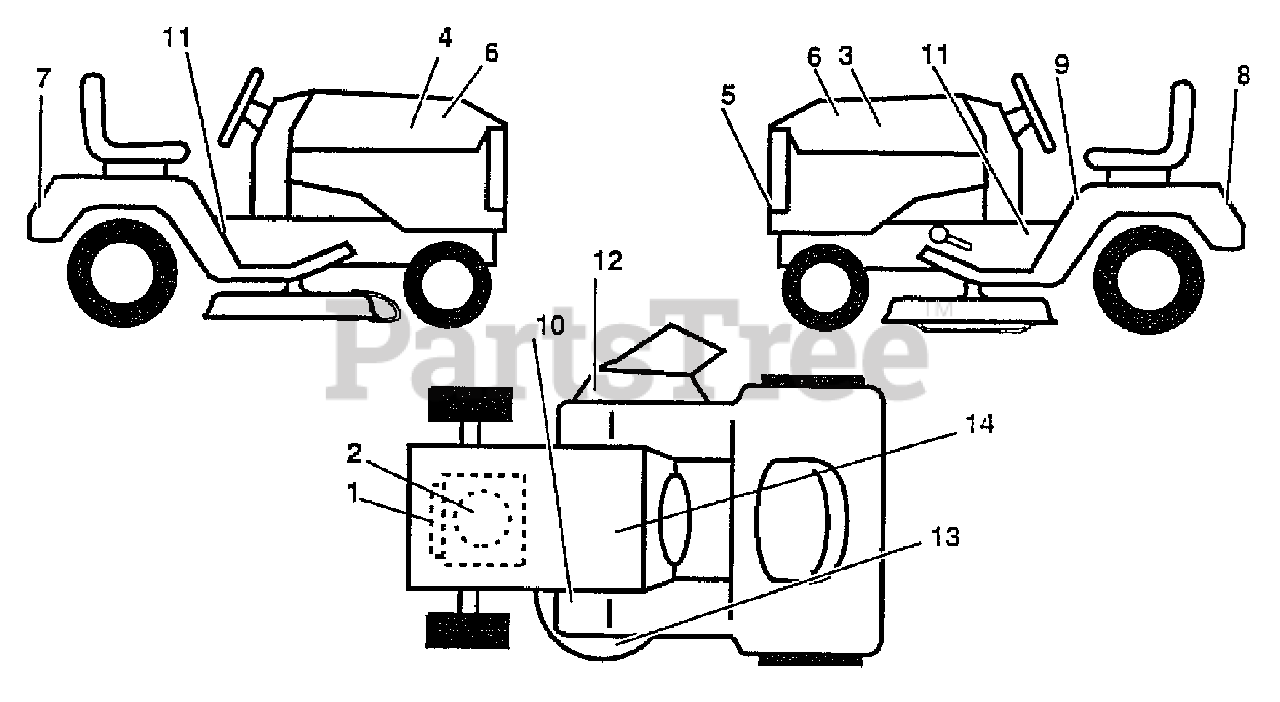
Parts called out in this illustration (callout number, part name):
1	Decal, Engine Instruction
2	Decal, Air Cleaner, HP
3	Decal, Hood Stripe, L.H.
4	Decal, Hood Stripe, R.H.
5	Decal, Grill
6	Decal, Side Panel
7	Decal, Fender
8	Decal, USA
9	Decal, Fender
10	Decal, Clutch/Brake
11	Decal, Chassis
12	Decal, Danger
13	Decal, Caution
14	Decal, Battery
